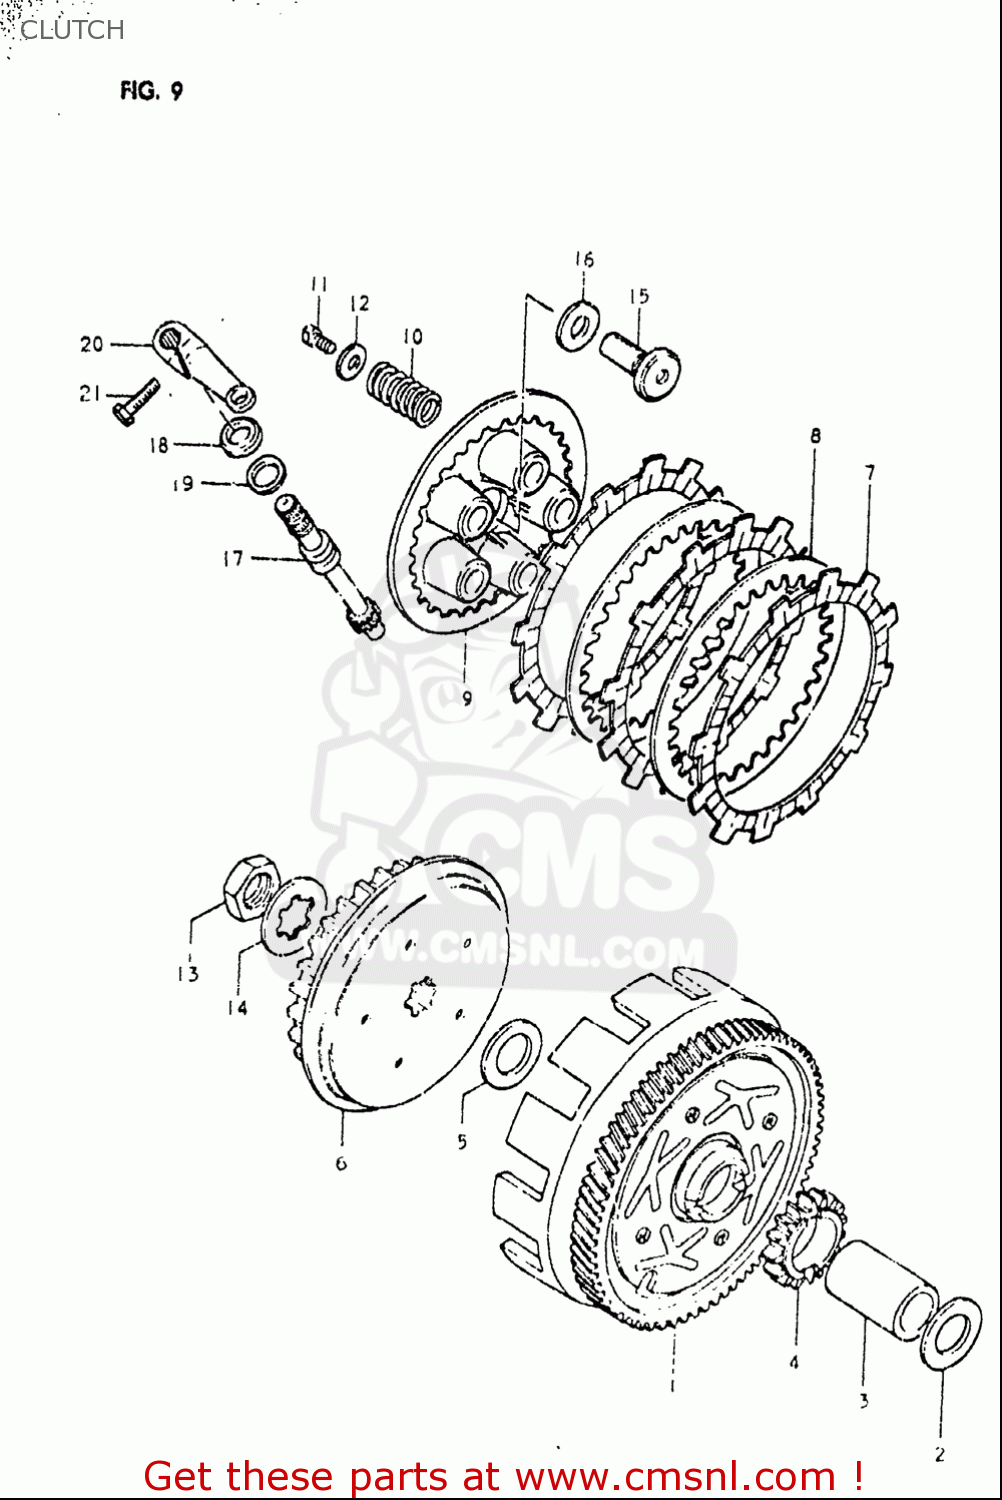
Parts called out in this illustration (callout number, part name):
1	GEAR ASSY,PRI DRIVEN(NT:73)
2	SHIM(17X30X1)
3	SPACER,PRIMARY DRIVEN GEAR
4	GEAR,KICK STARTER DRIVEN
5	WASHER
6	HUB,CLUTCH SLEEVE
7	PLATE,CLUTCH DRIVE(T:3.0) (NAS)
8	PLATE,CLUTCH DRIVEN (NAS)
9	DISC,CLUTCH PRESSURE
10	SPRING
11	BOLT(5X16)
12	WASHER(5.5X16X1.2)
13	NUT
14	WASHER,LOCK
15	RACK,CLUTCH RELEASE
16	BEARING(10X22X2.8)
17	PINION,CLUTCH RELEASE
18	SEAL,OIL(10X17X5)
19	WASHER(12.5X17X1)
20	ARM,CLUTCH RELEASE
21	BOLT
